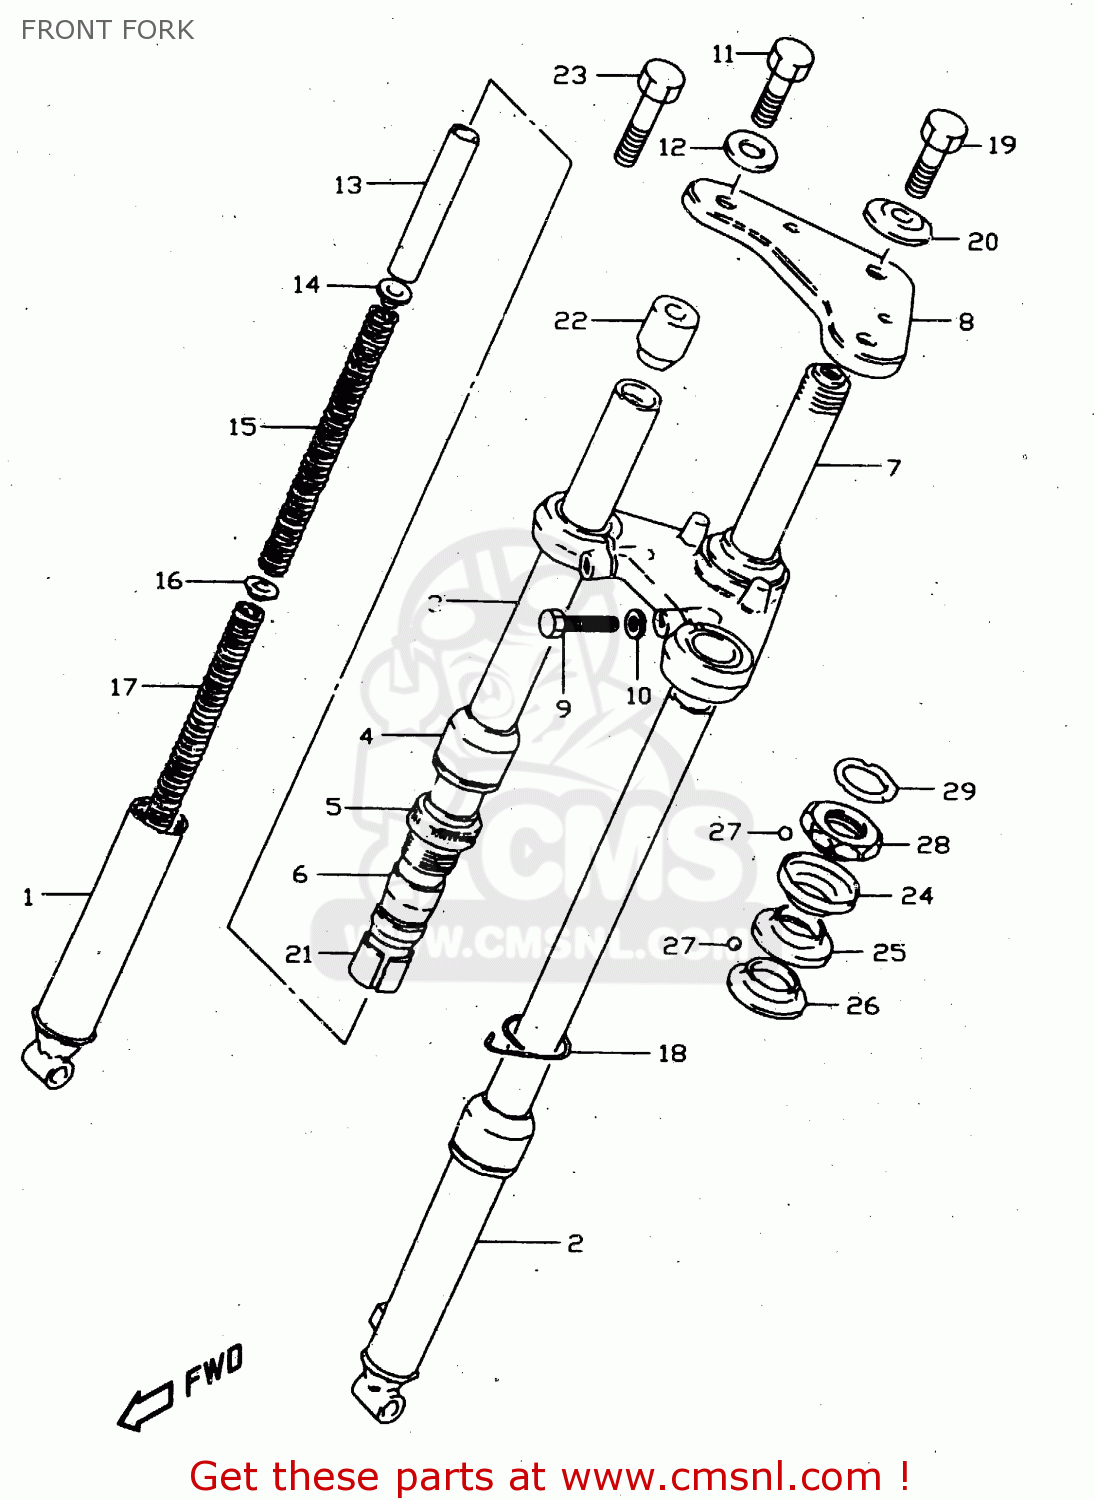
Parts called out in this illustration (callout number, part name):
1	TUBE,OUTER,R
2	TUBE,OUTER,L
3	TUBE,INNER
4	SEAL,DUST
5	NUT,OUTER
6	STOPPER
7	STEM,STEERING
8	HEAD,STEERING STEM
9	BOLT
10	WASHER,LOCK
11	BOLT
12	WASHER,STEERING STEM HEAD
13	SPACER
14	GUIDE,SPRING
15	SPRING,NO.1
16	GUIDE,SPRING NO.2
17	SPRING,NO.2
18	CLIP
19	BOLT
20	WASHER(33.5X10.5X4.2)
21	BUSH,SLIDE(33221-00801)
22	SPACER,FR FORK INNER TUBE
23	BOLT,FRONT FORK INNER TUBE
24	RACE,STEERING,INNER,UPPER
25	RACE,STEERING,INNER,LOWER
26	RACE,STEERING,OUTER,LOWER
27	BALL
28	RACE,STEERING,OUTER,UPPER
29	NUT
